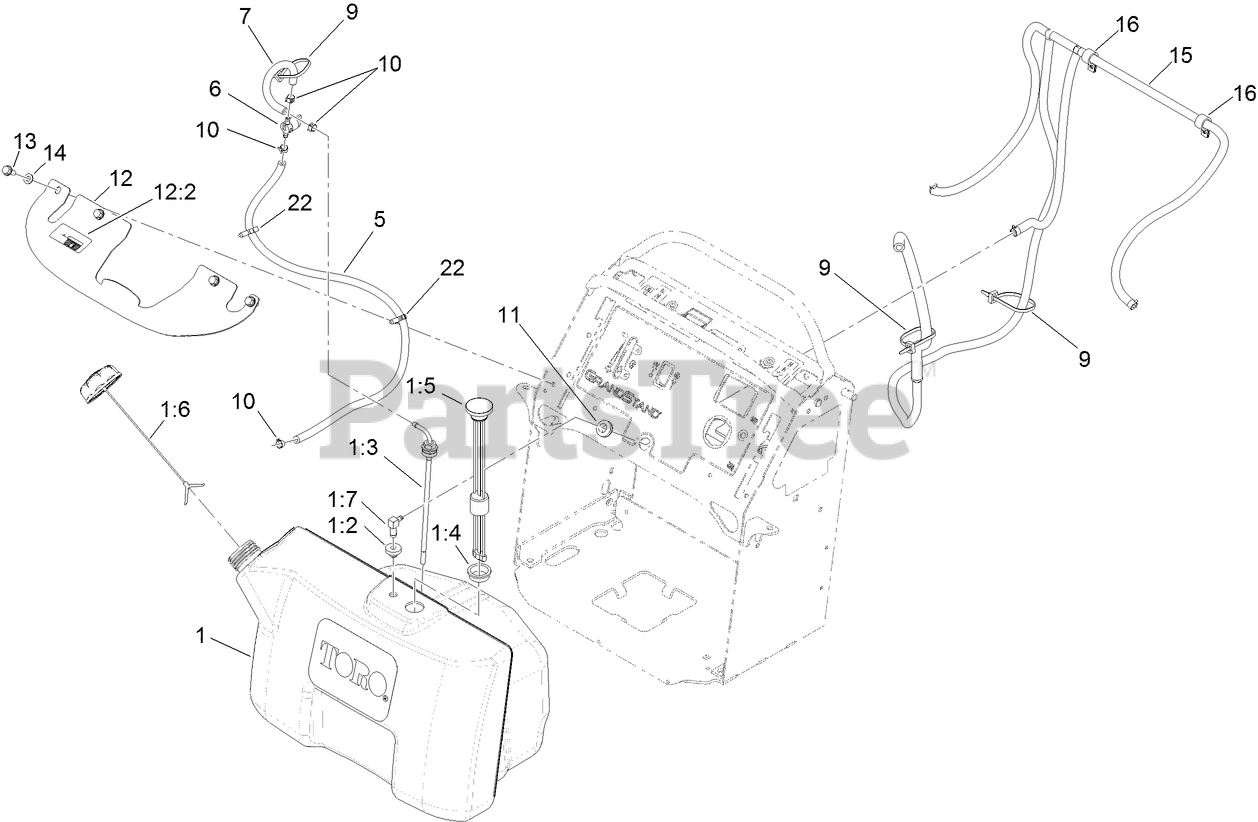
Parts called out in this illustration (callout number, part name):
1	TANK ASM
1:2	BUSHING
1:3	ELBOW-90 DEG
1:4	GROMMET
1:5	GUAGE-FUEL
1:6	CAP-FUEL, RATCHETING
1:7	FITTING-FUEL, BULKHEAD
5	HOSE-FUEL
6	VALVE-FUEL
7	HOSE-FUEL
9	TIE-CABLE
10	CLAMP-HOSE
11	GROMMET
12	BRACKET-TANK
12:2	DECAL-FILL, FUEL
13	SCREW-HWHTF
14	WASHER-FLAT
15	VENT HOSE ASM
16	CLAMP-CABLE
22	CLIP-HARNESS
